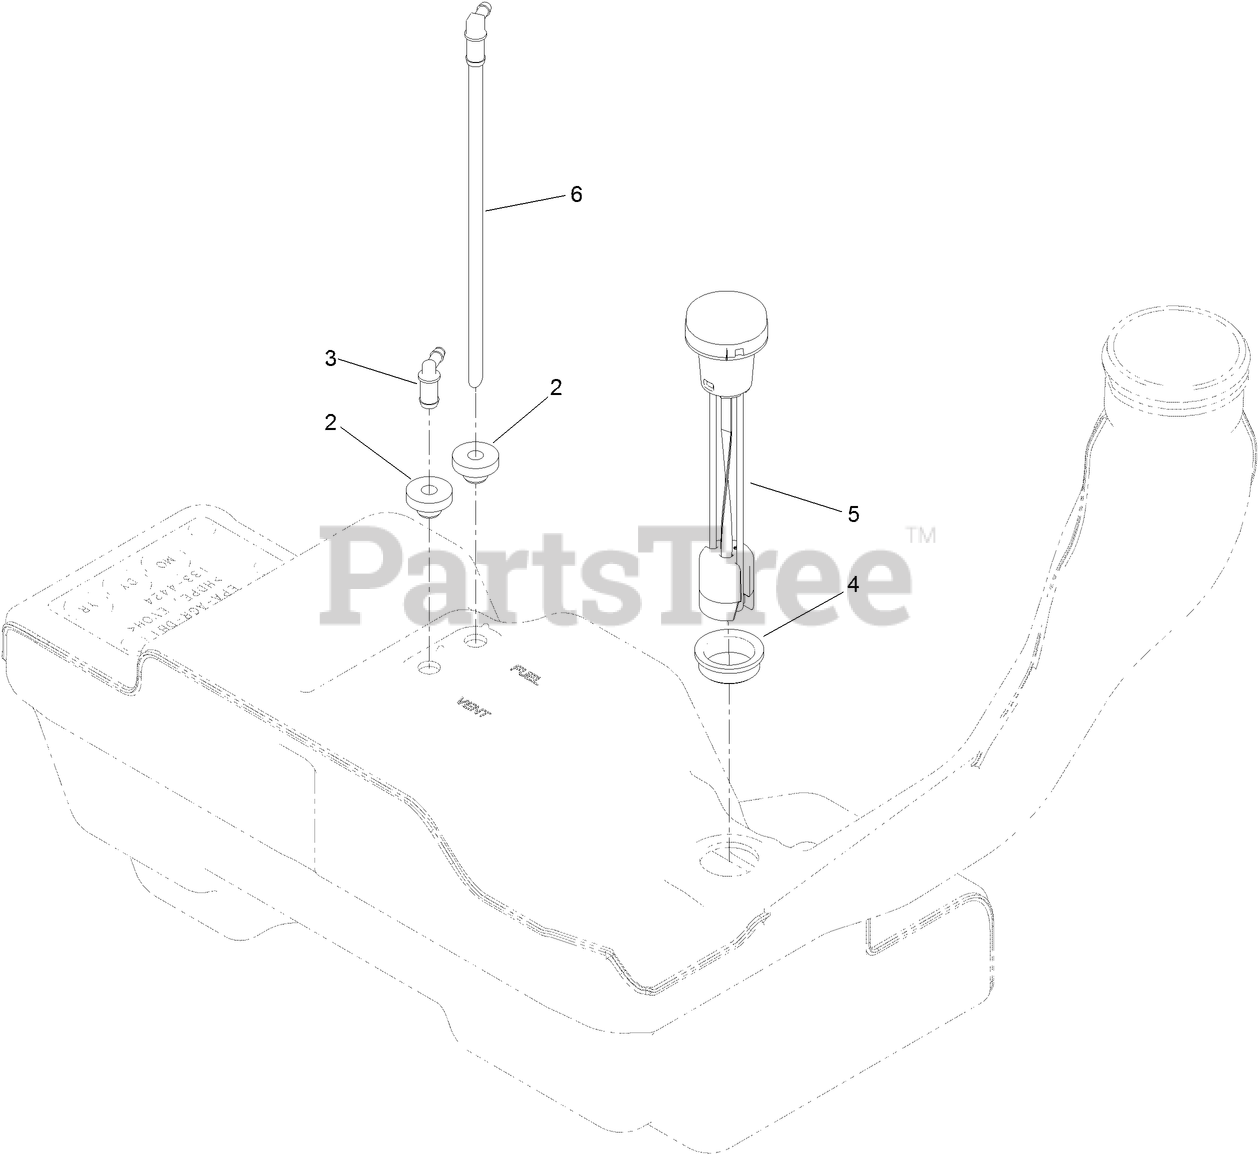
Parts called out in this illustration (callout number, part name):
2	BUSHING
3	FITTING-PLASTIC
4	GROMMET-FUEL
5	GAUGE-FUEL
6	CONNECTOR-ELBOW, 90 DEG
